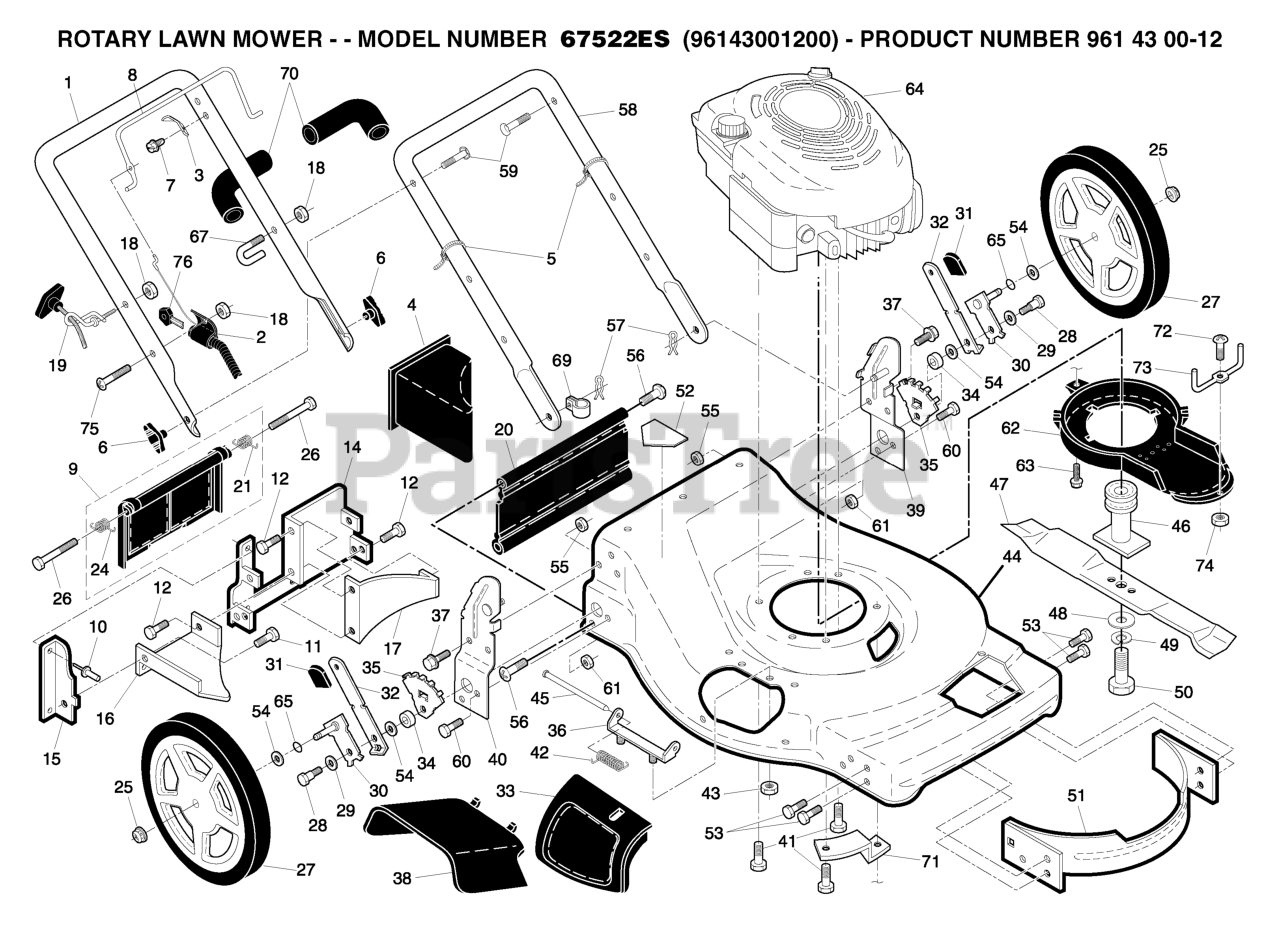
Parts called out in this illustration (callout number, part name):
1	RP HANDLE.ASM.UPPER.W/GRI
2	KIT.CONTROL.COMBI.KEYW/HARNESS
3	BRACKET UPSTOP
4	PLUG.MULCH.22RD
5	TIE GUIDE
6	HNDL.KNOB.GRAY
8	BAIL.DSTRT.FL.AW.CREAS.ORANGE
9	KIT.DOOR.ASM.REAR.PLAZ.22
10	RIVET BLIND
11	SCREW.HXTAP.10-24
14	PLATE.BACK
15	SIDE BAFFLE
16	DISCHARGE BAFFLE
17	REAR BAFFLE
18	NUT
19	RB GUIDE.ROPE.STD.BLK.ZIN WSL
20	SKIRT
21	DOOR SPRING LH
24	DOOR SPRING RH
25	NUT
28	BOLT
30	ARM.ASM.AXLE.12/14 REC.WHL
31	KNOB, SELECTOR SPRING
32	SPRING.SELECTOR.EXTENSION
33	DOOR.MULCH.22.REAR.FWGD.GREY
34	RP SPACER HT ADJ
35	WHEEL ADJ BRKT
36	BRACKET.ASM.HINGE.21.FWGD.
37	SELF-TAPPING SCREW 5/16-18X3/4
38	DEFLECTOR,CLIPPING
39	BRKT.ASM.HND
40	BRKT.ASM.HND
41	BOLT 3/8-16X1-1/8
42	SPRING.TORSION
43	LOCKNUT.NYLOC.1/4-20
45	ROD.HINGE.21
46	RP ADAP.BLDE/PULL
48	WASHER,HARDEN
49	LOCKWASHER
50	SCREW, HEX HD 3/8-24 X 1-3/8
51	FRONT BAFFLE KIT
52	DECAL HYT
53	SCREW 1/4X20
54	WASHER.FLAT.1/2
55	LOCKNUT PM
56	HINGE SCREW
57	HAIRPIN COTTER
59	BOLT, HANDLE 5/16-18X1.75
61	LOCKNUT PM
62	DEBRIS.SHIELD.FWGD.TOR
63	SCREW.HEX.WSH
65	O-RING..070X.487.NEOPRENE
69	CLIP.CABLE.BLK
70	GRIP.HANDLE.FOAM.WIDE.(1 SIDE)
71	BRACKET
72	SCREW.#8.MACH
73	KEEPER.BELT.FGD
74	NUT.HEX.#8
75	SCREW.(COMBINATION CONTROL)
76	KEY.MOLDED
